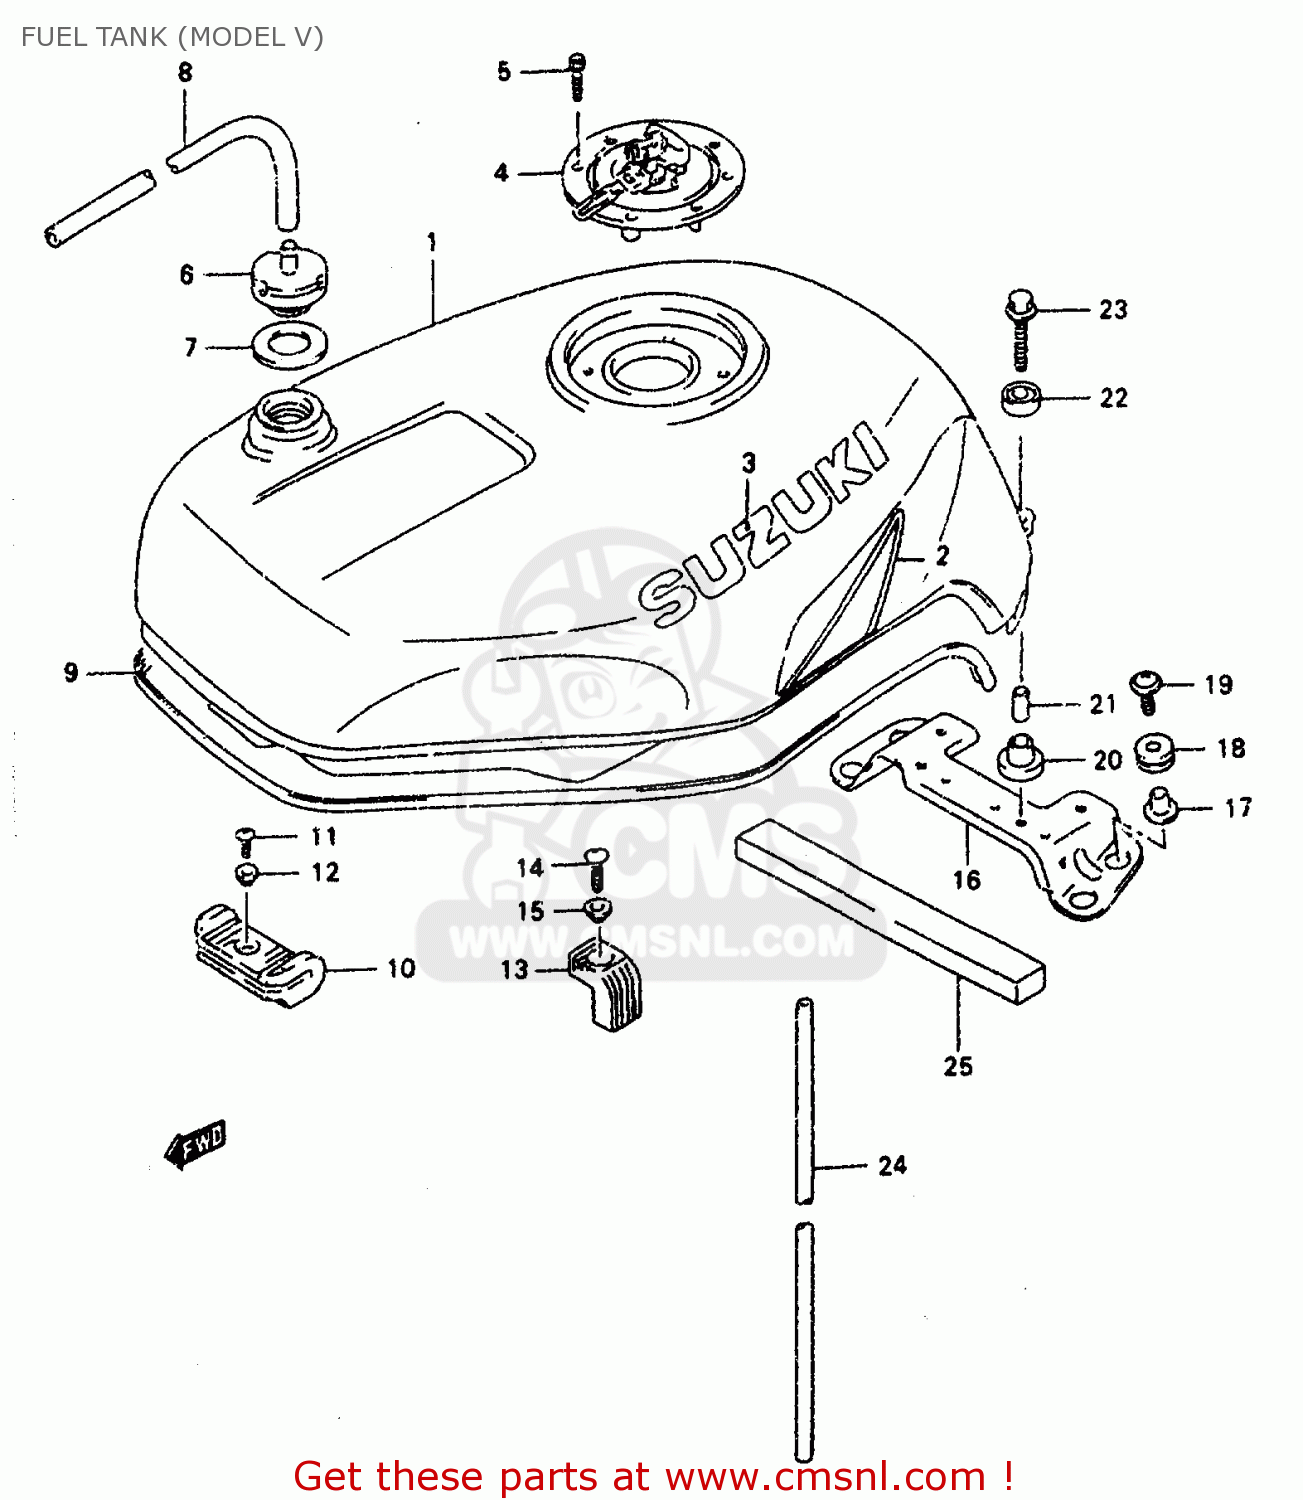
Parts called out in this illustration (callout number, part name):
1	TANK ASSY, FUEL
2	TAPE SET,FUEL TANK
3	EMBLEM,FUEL TANK
4	CAP SET,FUEL TANK
5	BOLT(5X20)
6	PLUG,FUEL TANK BREATHER
7	GASKET(12.5X20X2.5) (NAS)
8	HOSE(5X8.2X600)
9	MOLDING
10	CUSHION,FUEL TANK FR
11	SCREW
12	WASHER
13	CUSHION,TANK SIDE
14	SCREW
15	WASHER
16	BRACKET,FUEL TANK RR
17	WASHER
18	CUSHION
19	SCREW(6X25)
20	CUSHION
21	SPACER(6.5X9X18)
22	CUSHION
23	BOLT
24	HOSE(7X10.2X2000)
25	CUSHION,AIR SEAL
